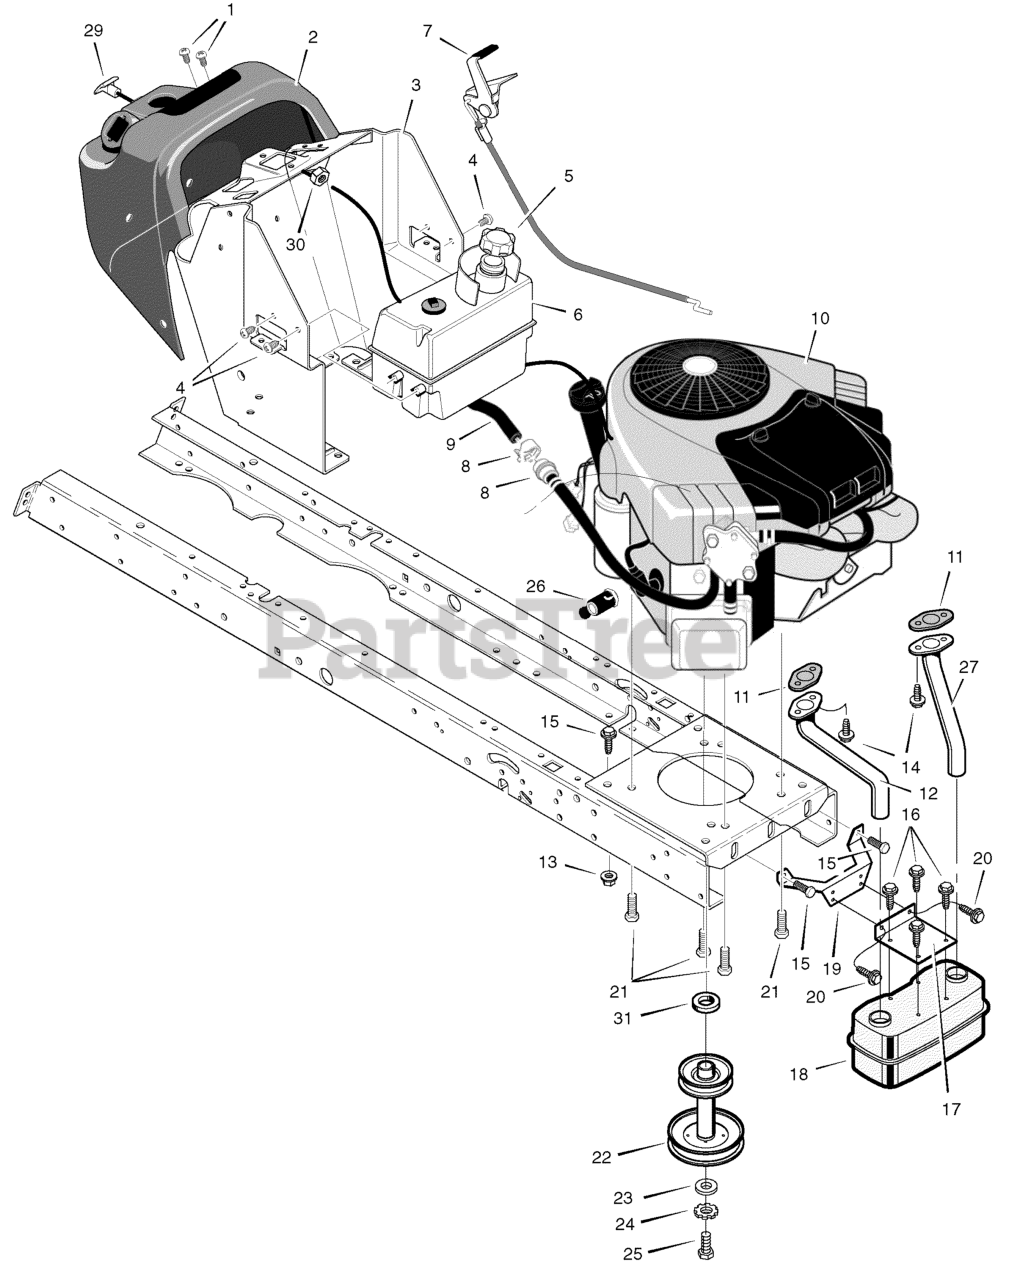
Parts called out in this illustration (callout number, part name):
1	Screw
3	Console
5	Cap, Fuel
6	Tank, Fuel
7	Control, Throttle
8	Clamp, Hose
9	Line, Fuel (Must cut to length)
10	Engine
11	Gasket, Exhaust
12	Tube, Right Exhaust
13	Nut
14	Bolt
15	Screw
16	Screw
17	Bracket, Muffler
18	Muffler
19	Bracket, Muffler Mount
20	Screw
21	Bolt, Engine Mount
22	Pulley, Stack
23	Washer
24	Washer
25	Bolt
26	Drain, Oil
27	Tube, Left Exhaust
30	Nut
31	Spacer
